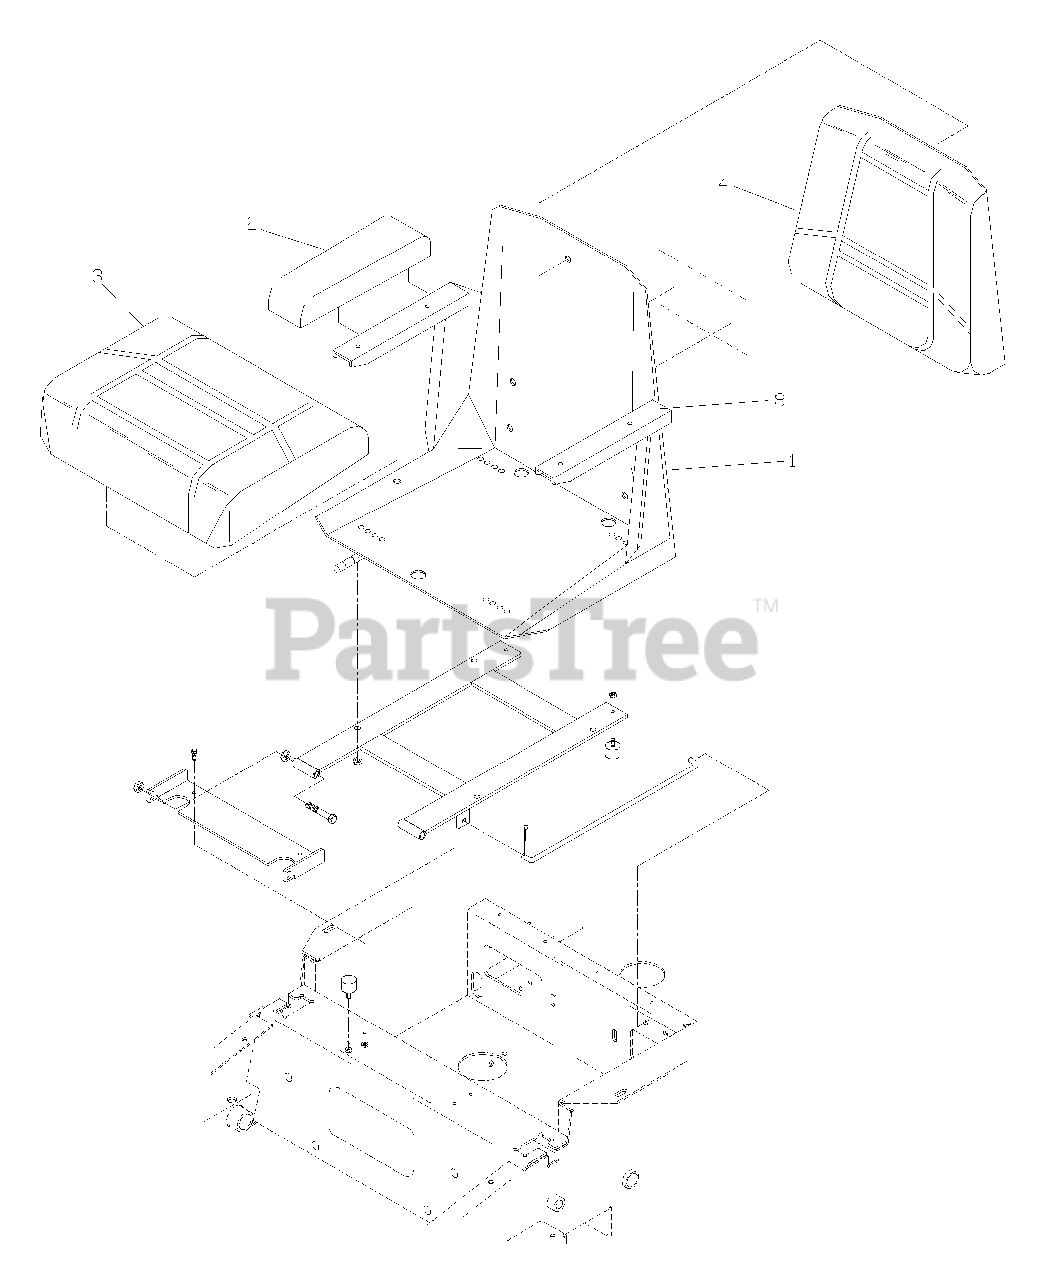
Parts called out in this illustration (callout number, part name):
1	SEAT, COMPLETE
2	ARM REST CUSHION
3	SEAT CUSHION
4	BACK CUSHION
5	SWITCH, SEAT
6	SEAT RAILS
7	SEAT HARNESS
8	SEAT ARM REST BKT.
